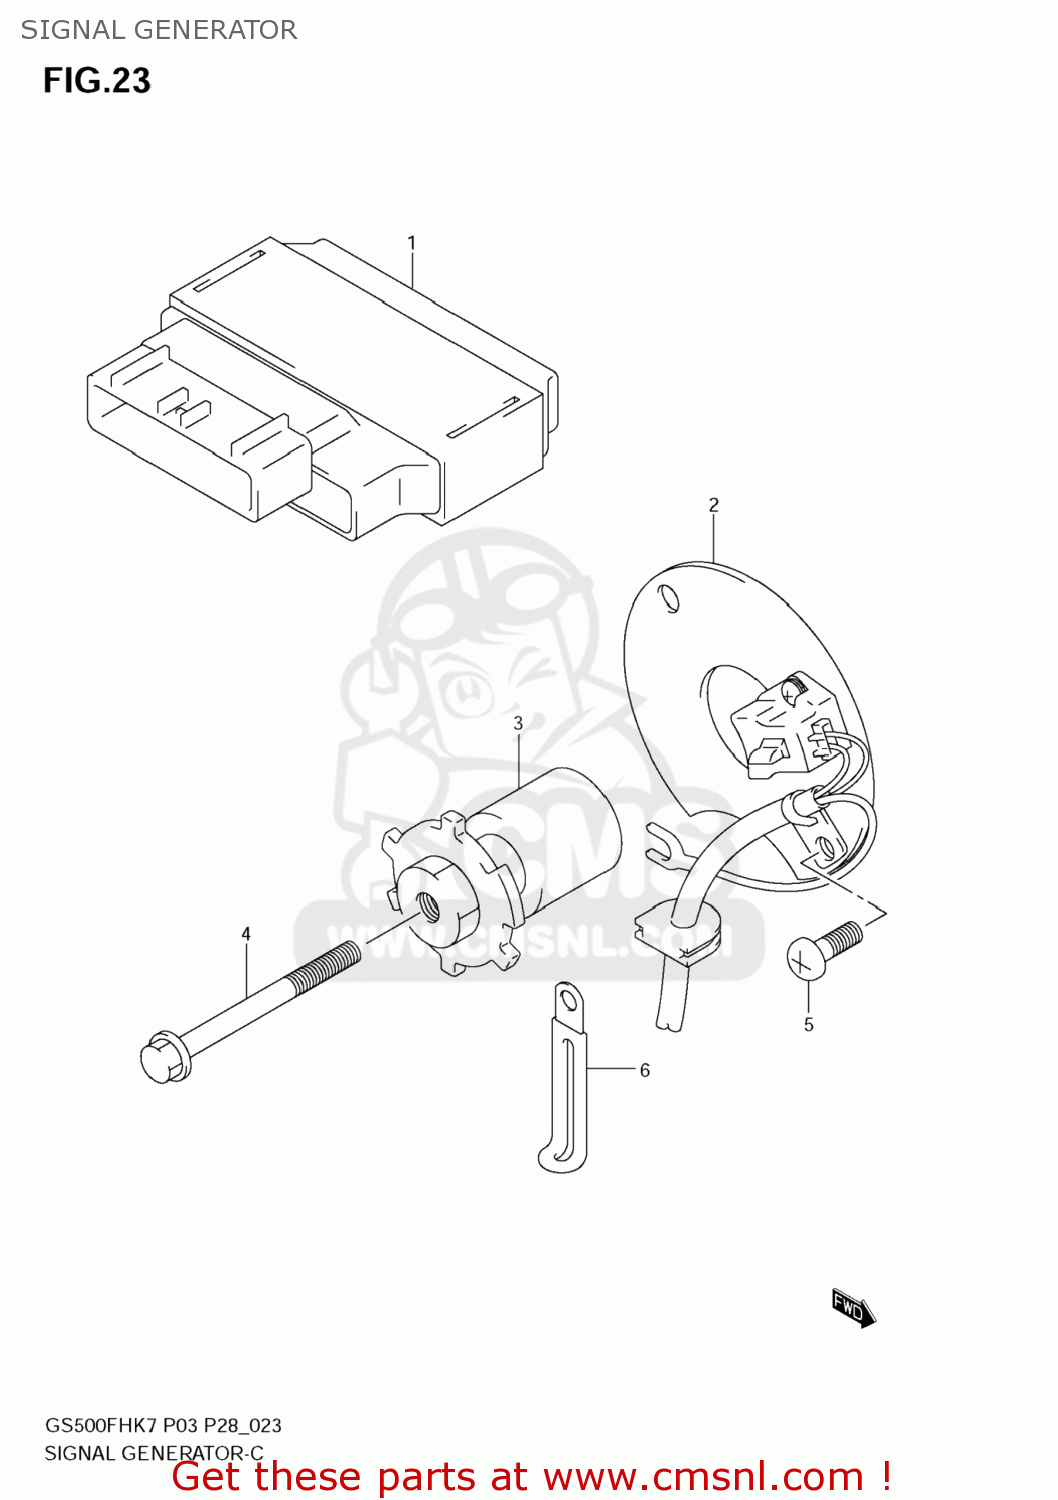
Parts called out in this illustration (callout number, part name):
1	IGNITOR ASSY
2	SIGNAL GENERATOR ASSY
3	ROTOR,SIGNAL
4	BOLT(6X60)
5	SCREW
6	CLAMP(L:45)
